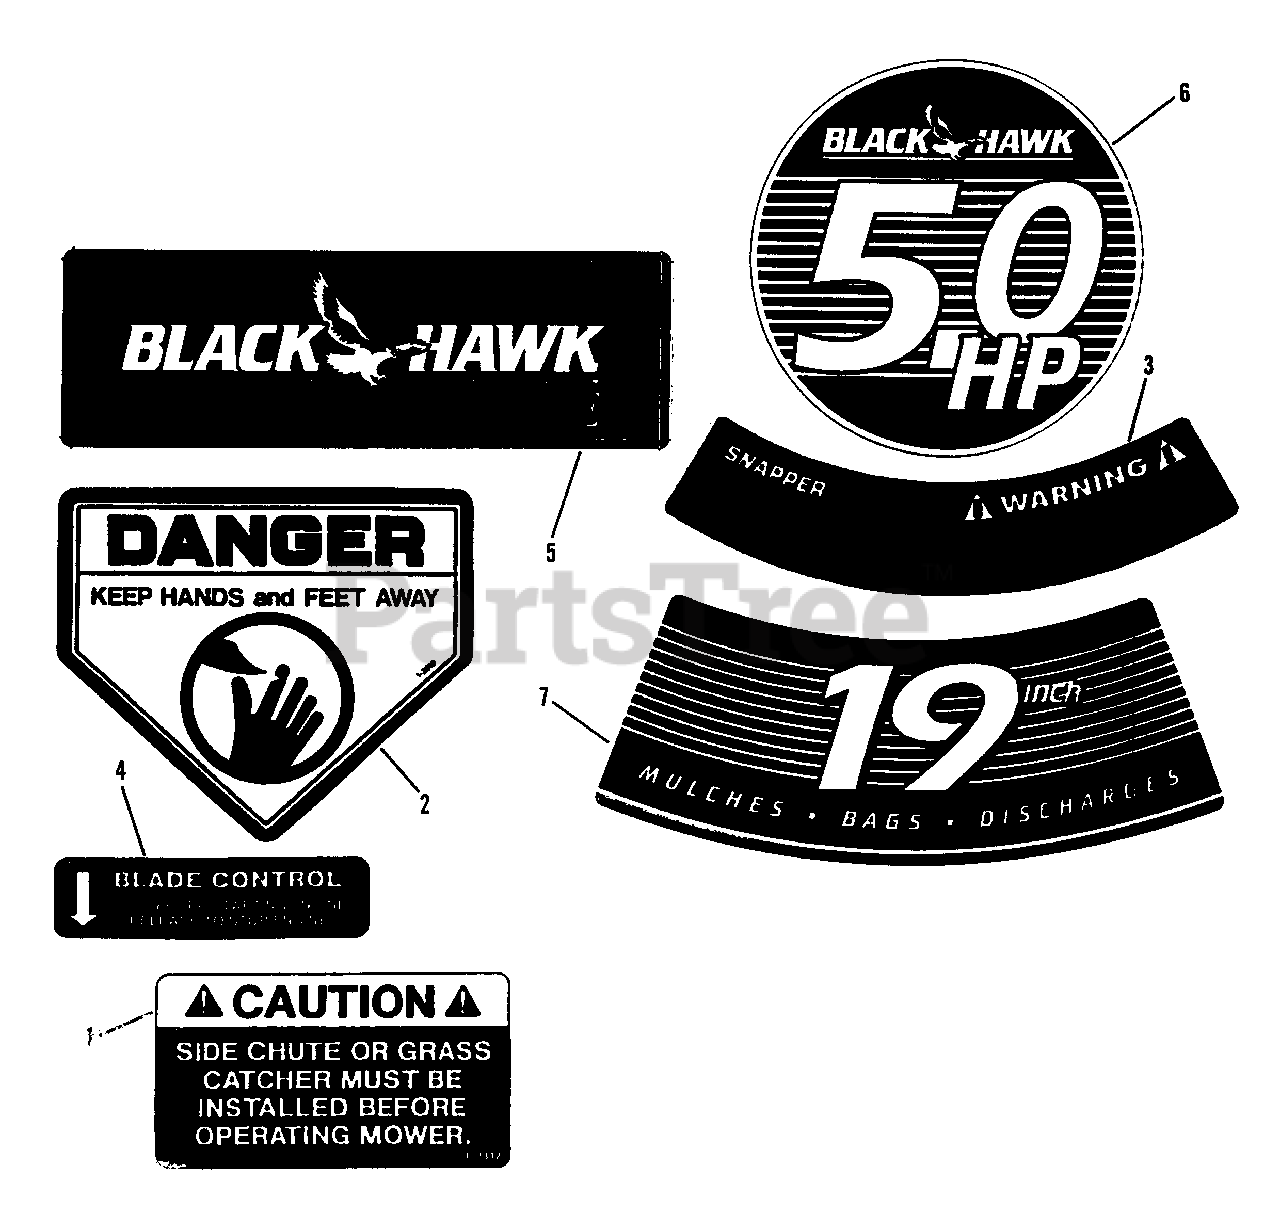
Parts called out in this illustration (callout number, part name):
1	DECAL, CAUTION
2	DECAL, DANGER
3	DECAL, WARNING
4	DECAL, Blade Control
5	DECAL, Front BLACKHAWK BH500
6	DECAL, Engine BLACKHAWK BH500
7	DECAL, Convertable BLACKHAWK BH500
